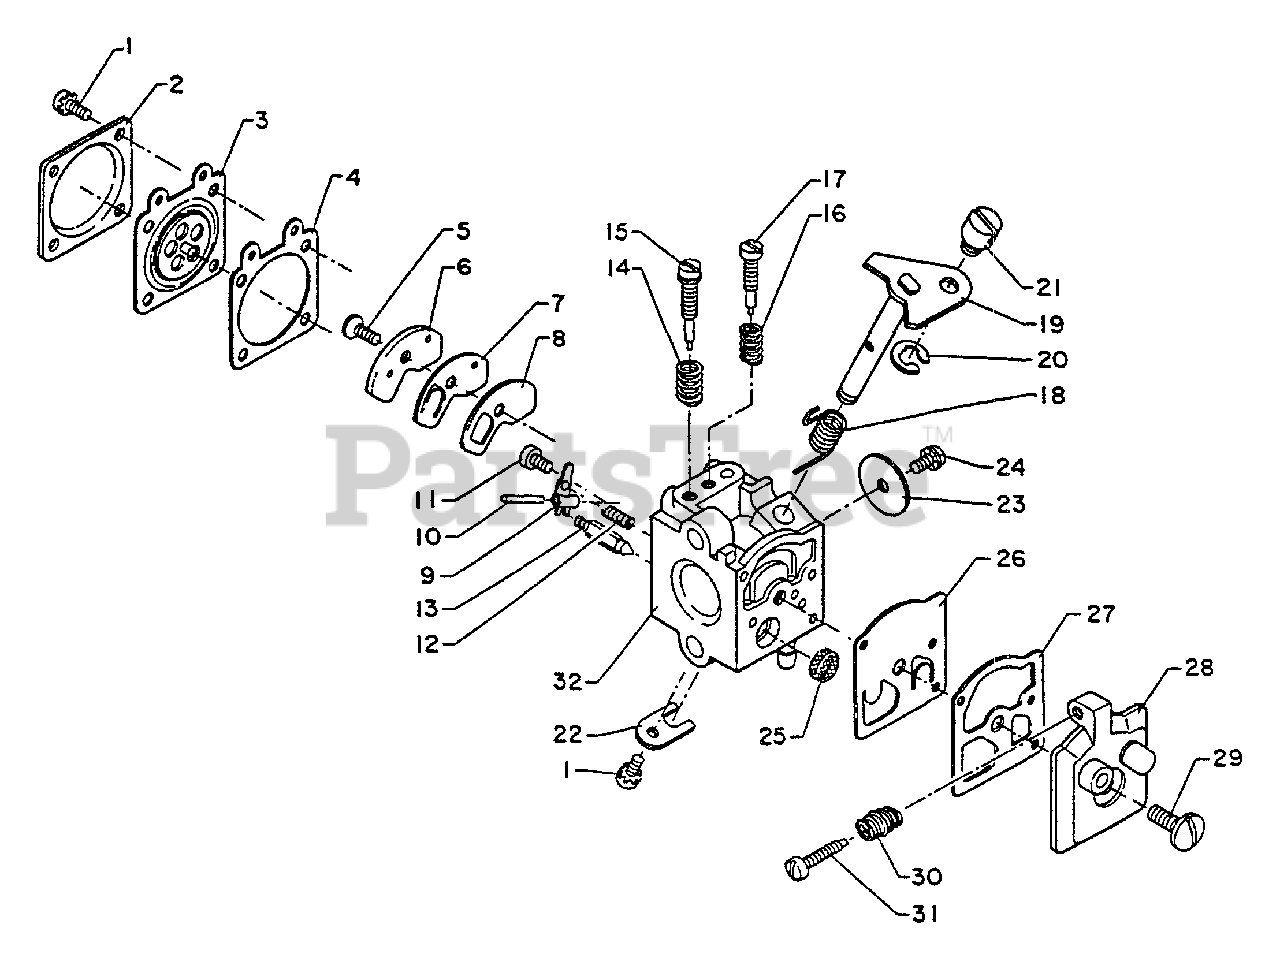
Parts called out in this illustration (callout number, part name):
1	REPAIR KIT, CARBURETOR
2	COVER, METERING DIAPHRAGM
3	REPAIR KIT, CARBURETOR
4	REPAIR KIT, CARBURETOR
5	REPAIR KIT, CARBURETOR
6	PLATE, CIRCUIT
7	REPAIR KIT, CARBURETOR
8	REPAIR KIT, CARBURETOR
9	REPAIR KIT, CARBURETOR
10	REPAIR KIT, CARBURETOR
11	REPAIR KIT, CARBURETOR
12	REPAIR KIT, CARBURETOR
13	REPAIR KIT, CARBURETOR
14	REPAIR KIT, CARBURETOR
15	NEEDLE, HIGH SPEED
16	REPAIR KIT, CARBURETOR
17	NEEDLE, IDLE
18	SPRING, THROTTLE RETURN
19	SHAFT, THROTTLE
20	RING, RETAINING
22	CLIP, THROTTLE SHAFT
23	VALVE, THROTTLE
25	REPAIR KIT, CARBURETOR
26	REPAIR KIT, CARBURETOR
27	REPAIR KIT, CARBURETOR
28	COVER, PUMP
30	SPRING, IDLE ADJUST
31	SCREW, IDLE ADJUST
32	BODY, CARBURETOR
